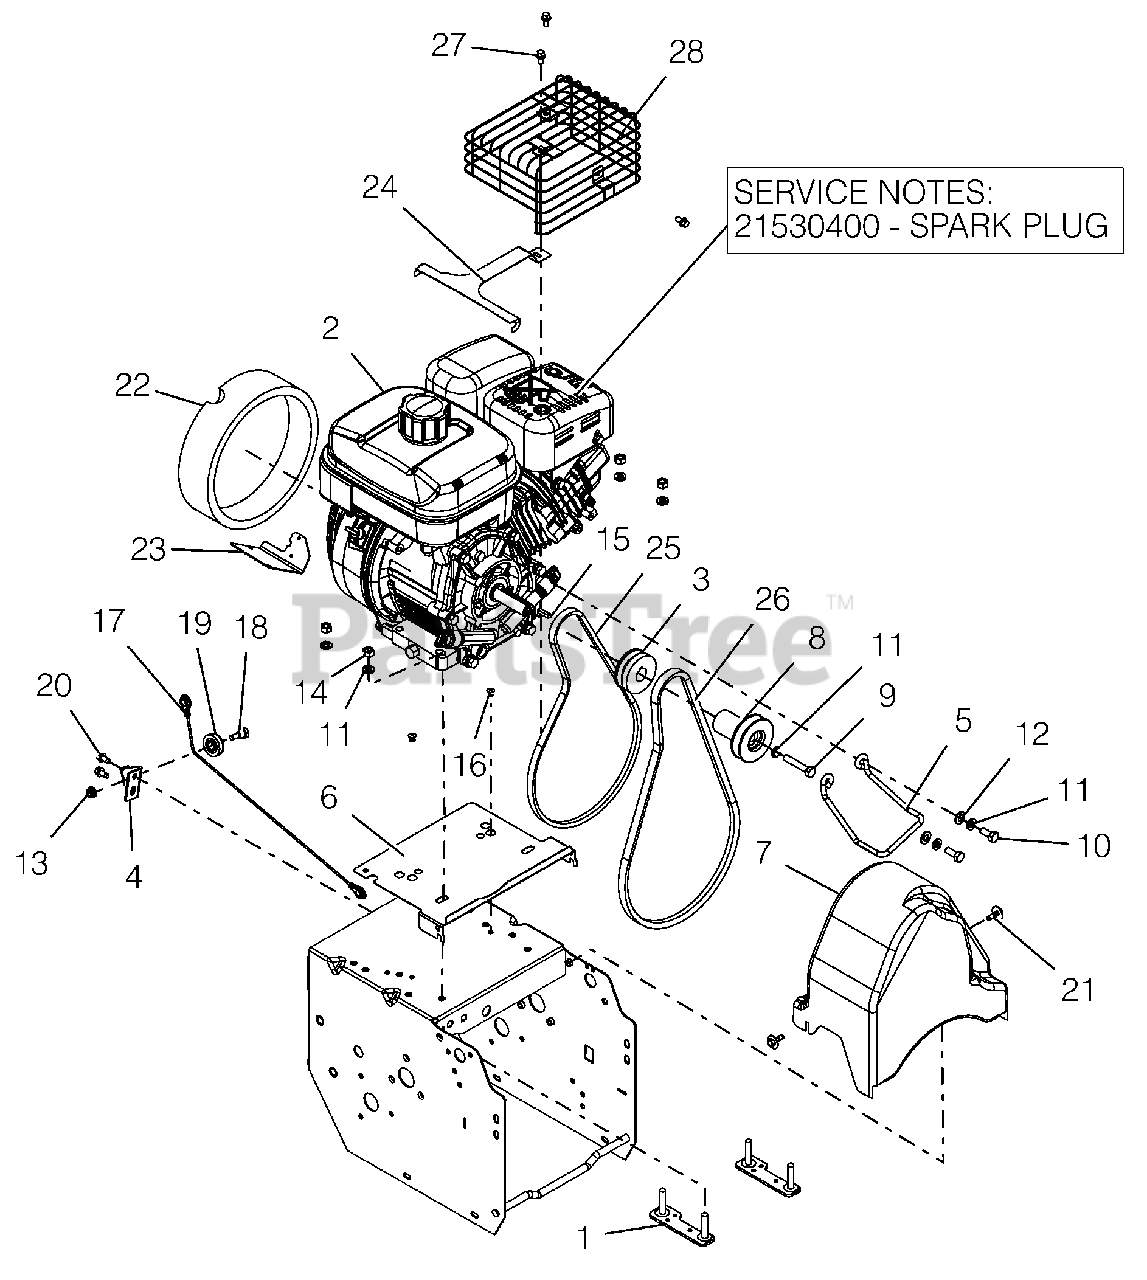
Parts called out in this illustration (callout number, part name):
1	STRAP, ENGINE BOLT-WELDMENT
2	SUBARU EX17 120V ALL-SEASON
2	PLUG, SPARK - TEC. SNO-THRO
3	PULLEY, TRACTION
4	BRACKET, CABLE PULLEY
5	BELT FINGER
6	BAFFLE, COMPACT
7	BELT COVER
8	SHEAVE, AUGER DRIVE
9	@BLT-HEX .31-24X1.75 GR5 YWZC
10	BLT-HEX .31-24X.75 YWZC GR5
11	WSHR-LK .312X.097 HVY YWZC
12	@WSHR-FL-STL.344X.688X.065YWZC
13	NUT-LK-CTR-FLG .25-20 YWZC
14	@NUT-HEX .31-18 YWZC
15	KEY-SQ .188X.75X.188
16	RVT-POP .187 YZ
17	CABLE, LOWER TRACTION (CMPCT)
18	BOLT, SHLDR-.375X.375X.25-20
19	PULLEY, CABLE
20	SCR-TAP .25-20X.50 HWH TR YWZ
21	SCR-TAP .25-20X.5 CAPTIVE
22	FOAM COVER, RECOIL-SUBARU
23	BRACKET, SWITCH-SUBARU
24	GUARD, SNOW-SUBARU EX17
25	V-BELT, 3L-WRAPPED
26	V-BELT, HA-RAW EDGE
27	BLT-SERHFWH M6X1.0X12 8.8 CZ
28	GUARD,MUFFLER,SUB 20A-37303-11
